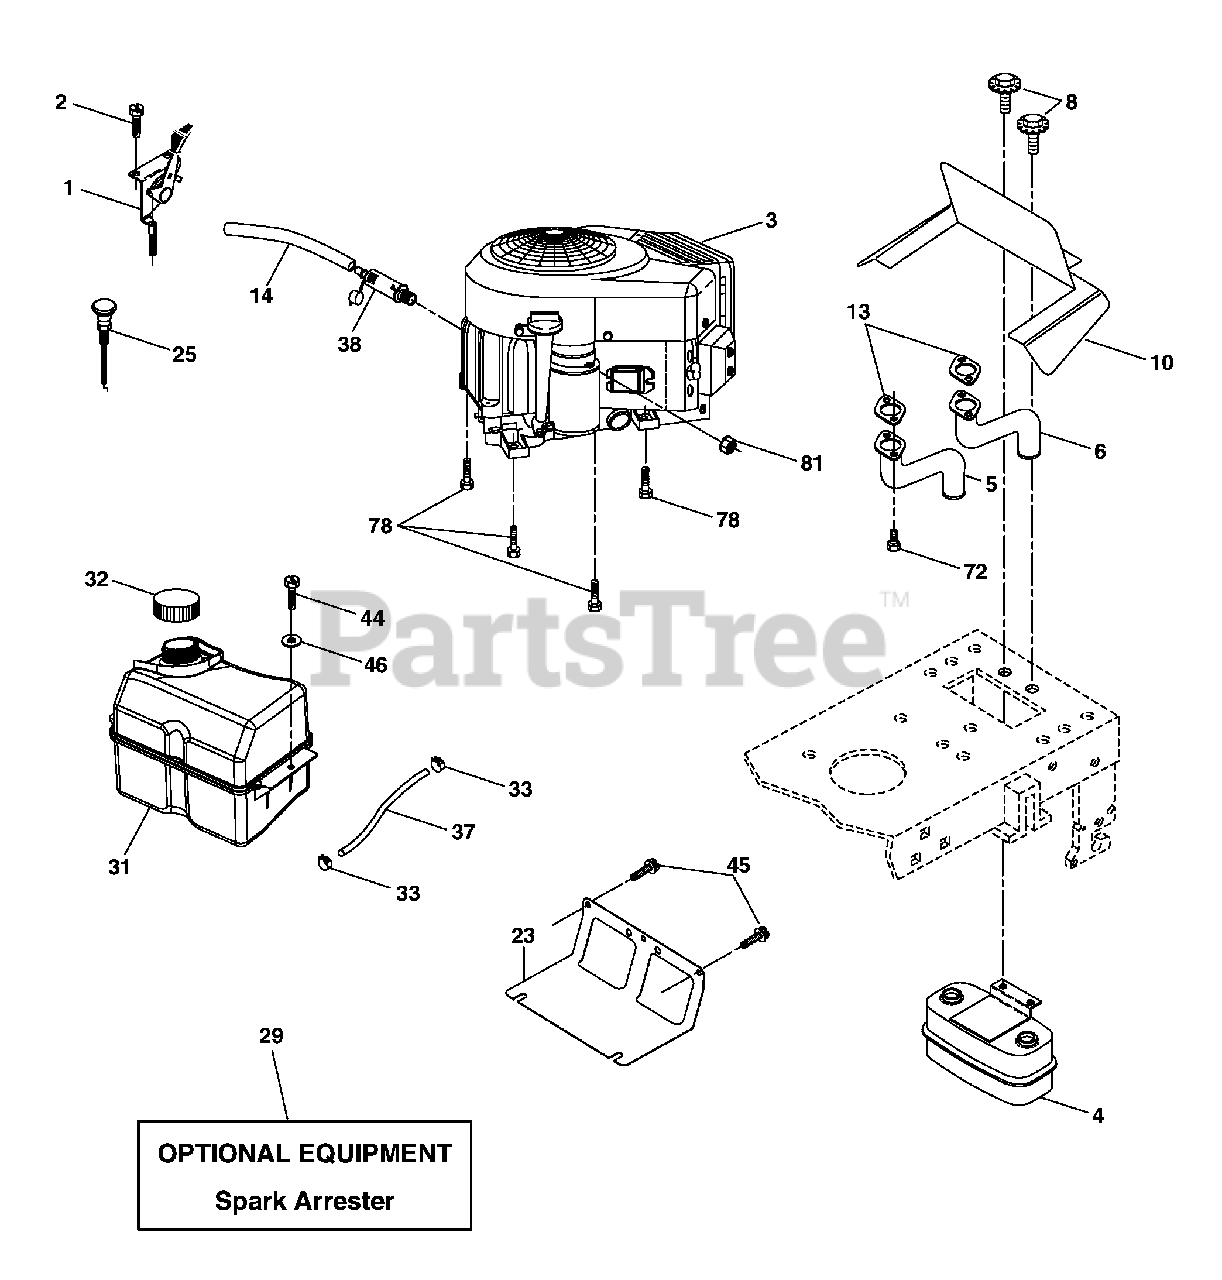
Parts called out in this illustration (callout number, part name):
1	Control, Throttle
2	Screw Hex Thd Cut 1/4-20 x 1/2
4	Muffler
5	Exhaust Tube LH
6	Exhaust Tube RH
8	Bolt 5/16-18 UNC x 3/4
10	Shield Browning
13	Muffler Gasket
14	Tube Oil Drain
23	Shield, Browning/Debris Guard
29	Arrester, Spark
31	Tank, Fuel
32	Cap, Fuel
33	Clamp, Hose Blk
37	Line, Fuel
38	Plug Drain Oil Easy
44	Screw Hex Wsh Thdrol 1/4-20 x 3/4
45	Screw Hex Wsh Thdrol 3/8-16 x 3/4
46	Washer 9/32 x 7/8 x 16 Ga.
72	Screw Hex 5/16-18 x 1
78	Screw 3/8-16 x 1-1/2
81	Nut Keps Hex 1/4-20 unc
